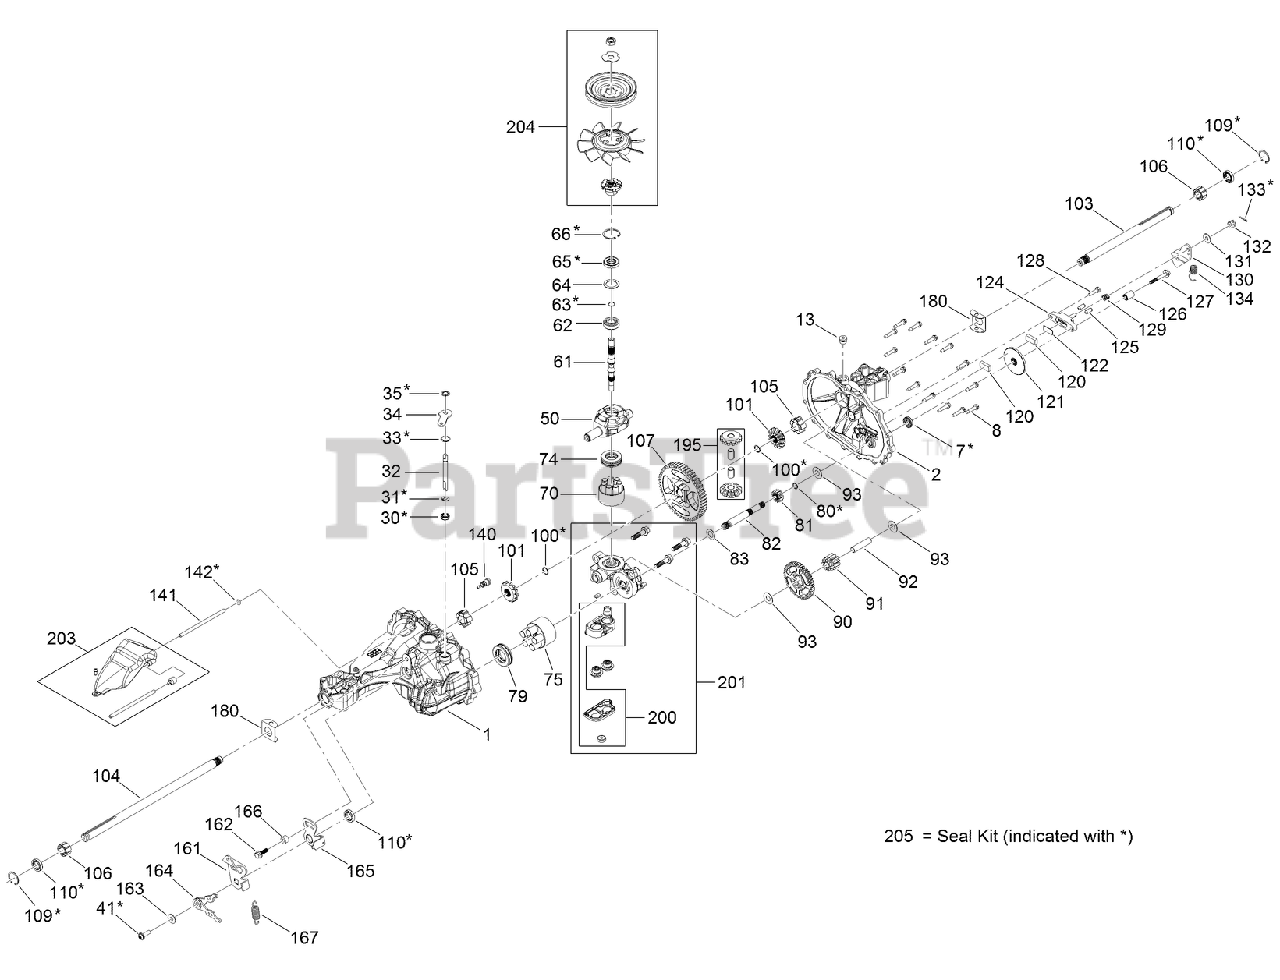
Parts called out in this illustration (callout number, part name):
1	MAIN HOUSING KIT
2	HOUSING SIDE KIT
7	SEAL-LIP
8	SCREW-HHF
13	PLUG-THREAD, STRAIGHT
30	SEAL-LIP
31	RING-RETAINING, EXTERNAL
32	ROD-BYPASS, ACTUATOR
33	RING-RETAINING, INTERNAL
34	ARM-BYPASS
35	RING-RETAINING, EXTERNAL
50	TRUNNION-PLATE, SWASH
61	SHAFT-INPUT
62	BEARING-SHAFT, BALL
63	RING-RETAINING, WIRE
64	SPACER
65	SEAL-LIP
66	RING-RETAINING
70	PISTON BLOCK ASM
74	BEARING-THRUST, BALL
75	CYLINDER BLOCK KIT
79	BEARING-THRUST
80	RING-RETAINING, EXTERNAL
81	GEAR-PINION
82	SHAFT-MOTOR
83	WASHER
91	GEAR-JACKSHAFT, 11T
92	PIN-JACKSHAFT
93	WASHER
100	RING-RETAINING, SPIRAL
101	GEAR-BEVEL, 12T (SPLINE, ID)
103	SHAFT-AXLE, KEYED
104	SHAFT-AXLE, KEYED
105	BUSHING-INBOARD
106	BUSHING-OUTBOARD
107	GEAR-53T, BULL
109	RING-RETAINING, INTERNAL
110	SEAL-LIP
120	PUCK-BRAKE
121	ROTOR-BRAKE
122	PUCK-PLATE
124	YOKE-BRAKE
125	PIN-BRAKE
126	SPACER
127	SCREW-HF
128	SCREW-HHCS
129	SPRING-BRAKE, ANTI DRAG
130	BRAKE-ARM
131	WASHER
132	NUT-CASTLE
133	PIN-COTTER
134	SPRING-ARM, BRAKE (BIAS)
140	FITTING-SAE
142	O-RING
161	ARM-CONTROL, RETURN
162	SCREW-HF
163	WASHER
164	BI DIRECTIONAL RETURN KIT
165	ARM-NEUTRAL
166	BUSHING
167	SPRING-EXTENSION
180	SPRING CLIP-HOUSING THRUST
195	MITER GEARS W/PINS KIT
200	FILTER KIT
201	CENTERSECTION W/FILTER KIT
203	EXPANSION TANK KIT
204	FAN/PULLEY KIT
205	SEAL KIT
